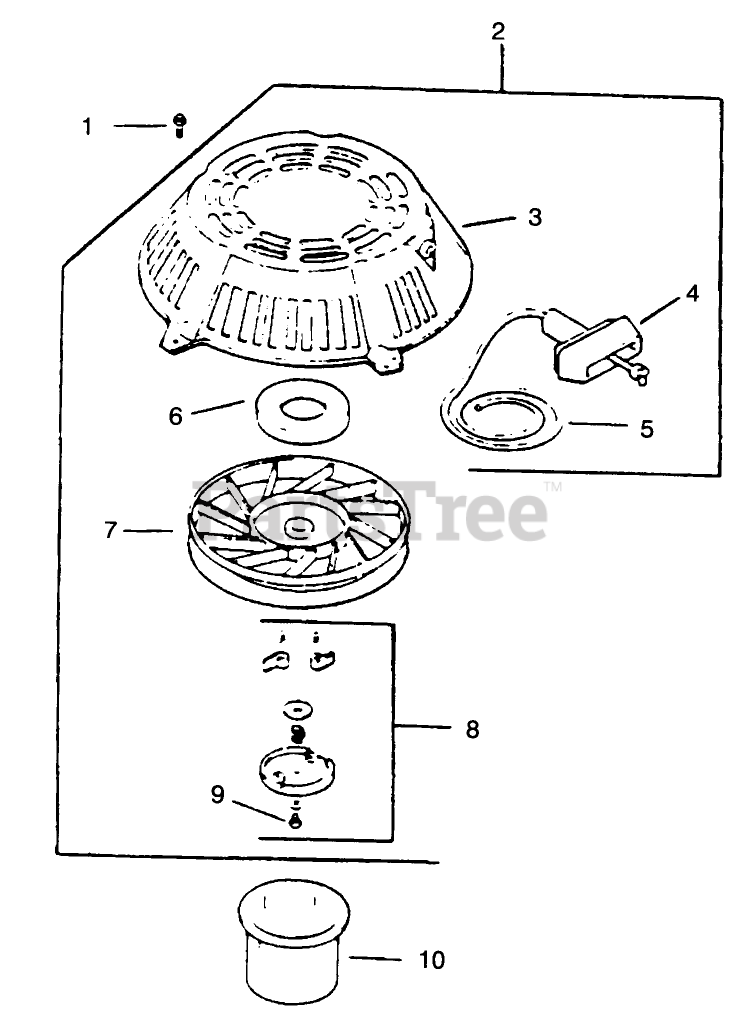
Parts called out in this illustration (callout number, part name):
1	Screw
2	Starter (Incl. Ref. #3-9)
3	Housing-Starter
4	Handle
5	Rope-Starter
6	Spring & Keeper
7	Pulley
8	Kit-Dog Replacement (Incl Ref. #9)
9	Screw-Posidrive
10	Cup-Driver
